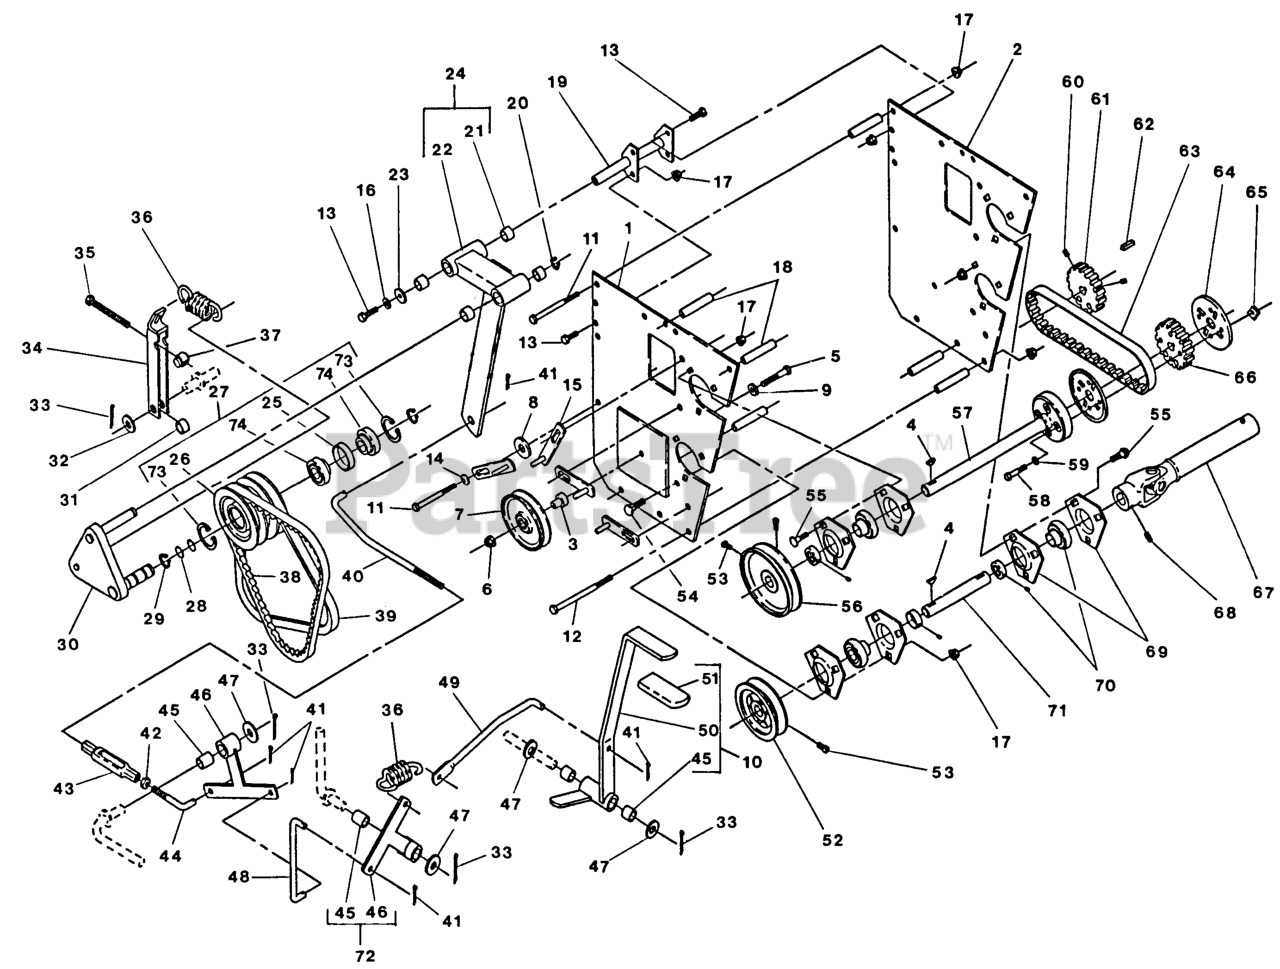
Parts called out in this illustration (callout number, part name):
4	KEY-WOODRUFF
12	SCREW-HH
14	WASHER-SPRING
16	WASHER-LOCK
22	Control Wldm't - Tmfr. Sheave
24	CNTRL ASSY,TRANS SHV
25	SPACER,TRANSFER BEARING
28	O-RING,
36	SPRING,BELT TENSION
37	SWIVEL,BELT TENSION
38	BELT,B SIZE 43.5
39	BELT,SECONDARY DRIVE
40	ROD,PTO LOW RH THD
44	ROD,PTO RH LOW LH THD
45	SLEEVE-BEARING
49	ROD,PTO UPPER
51	GRIP-LEVER
52	SHEAVE,5.5 B
53	SCREW-SET
56	SHEAVE,7 B
59	WASHER-LOCK
63	BELT,DRIVE POSITIVE
69	HOUSING-FLANGE
70	BEARING,W/COLLAR
71	JACKSHAFT,PTO
74	BEARING
